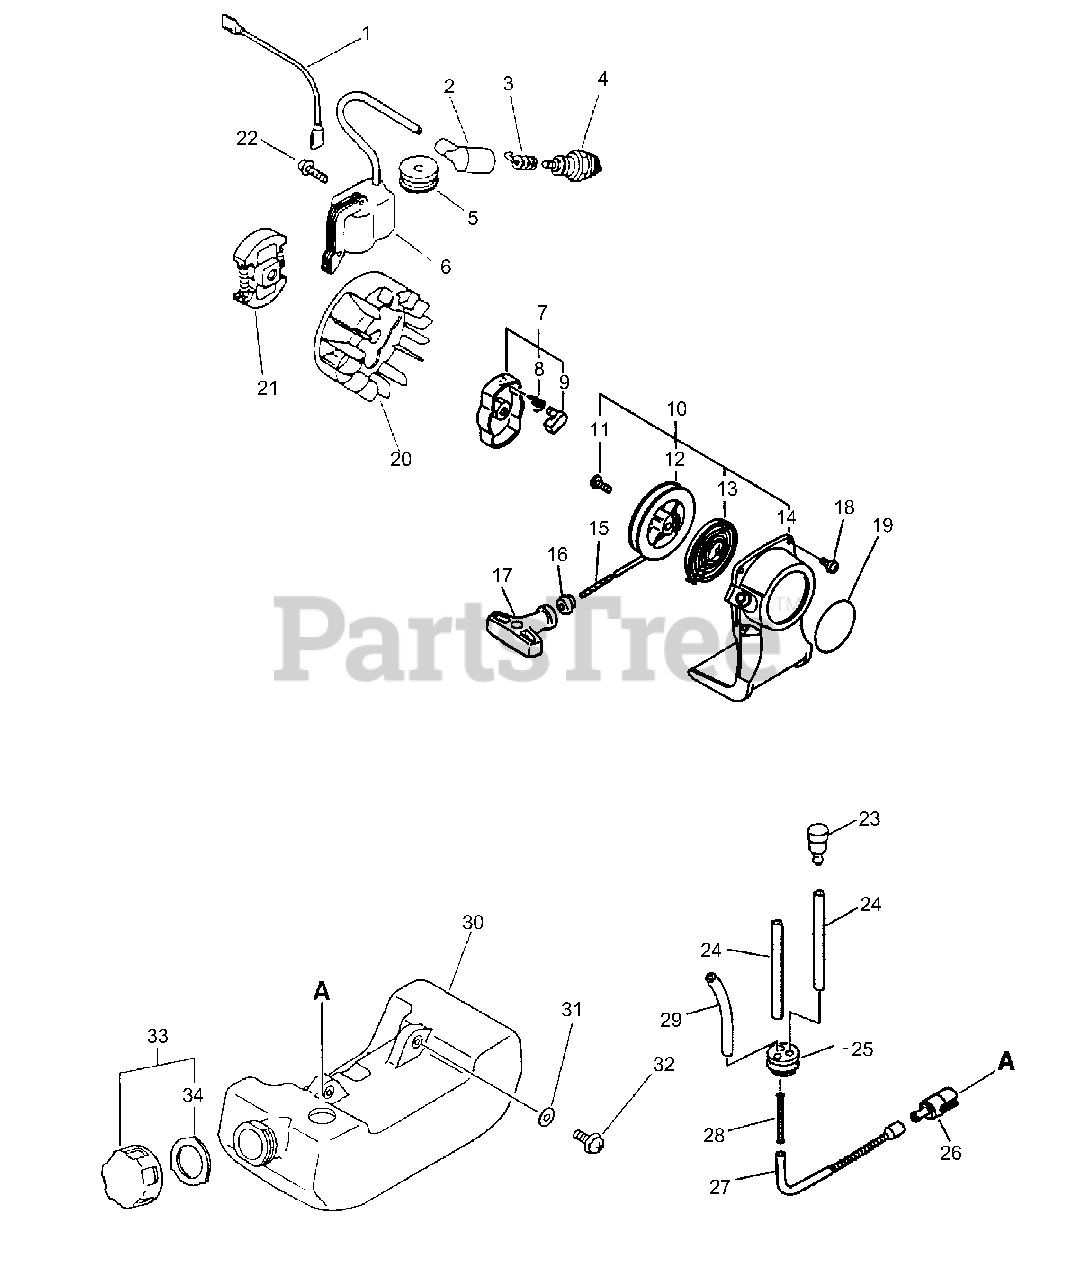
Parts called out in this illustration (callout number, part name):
1	LEAD
2	CAP, SPARK PLUG
3	TERMINAL, SPARK PLUG
4	SPARK PLUG - BPM7A
4	SPARK PLUG - BPMR7A
6	COIL, IGNITION
7	PAWL ASSY, STARTER
8	SPRING, RETURN
9	PAWL, STARTER - BLACK
10	STARTER ASSY
11	SCREW
12	REEL, ROPE
13	SPRING, RECOIL
14	CASE, STARTER
16	GUIDE, ROPE
17	GRIP, STARTER
18	BOLT 4×16
19	LABEL, ECHO
21	CLUTCH ASSY
22	SCREW 4×22
23	VENT ASSY
24	PIPE, FUEL 3x-5x-70 BLACK
25	GROMMET, FUEL
26	FILTER, FUEL
27	PIPE, FUEL 3×7×100 FLEXIBLE
28	CONNECTOR, PIPE
29	PIPE, FUEL RETURN 3×6×90 MM CLEAR
30	TANK, FUEL
31	WASHER 5.5×12×0.8
32	SCREW 5×16
33	CAP ASSY, FUEL
34	GASKET, FUEL CAP
